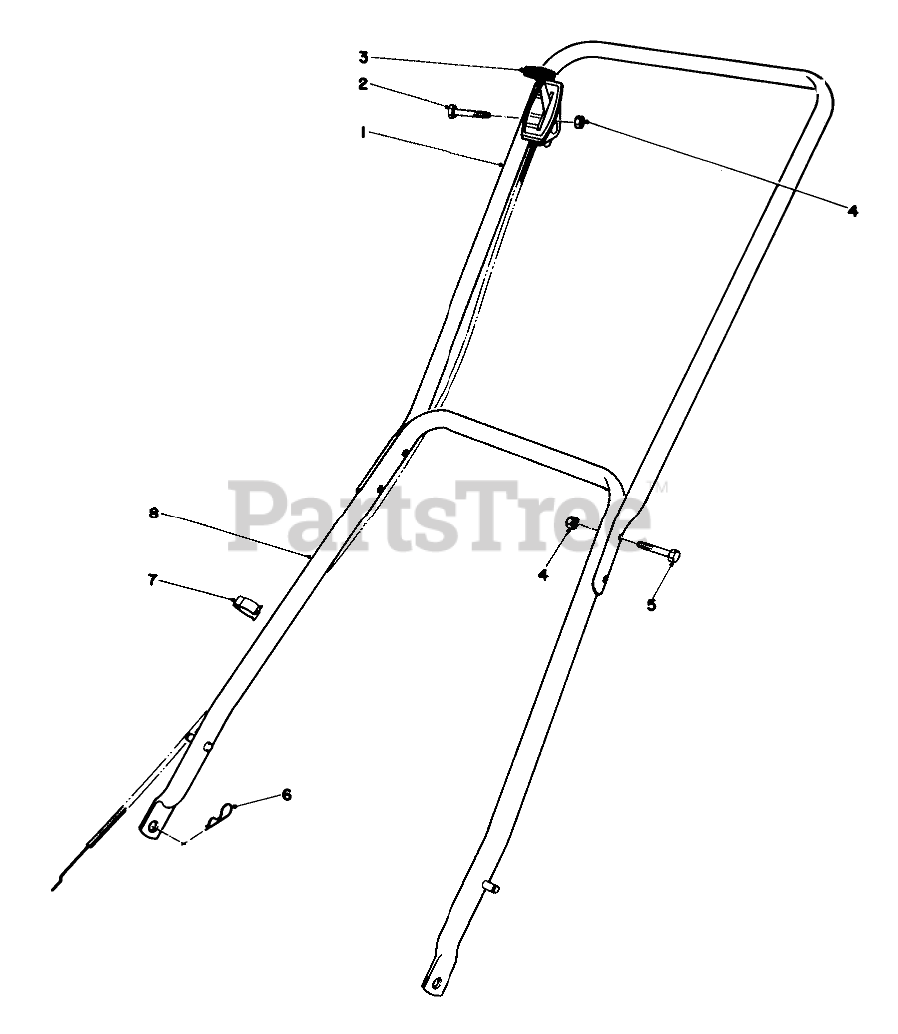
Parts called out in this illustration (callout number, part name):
1	UPPER HANDLE
2	SCREW-HH
3	THROTTLE CONTROL
4	NUT-LOCK
5	SCREW-HH
6	PIN-COTTER, HAIR
7	Clamp
8	LOWER HANDLE WA
